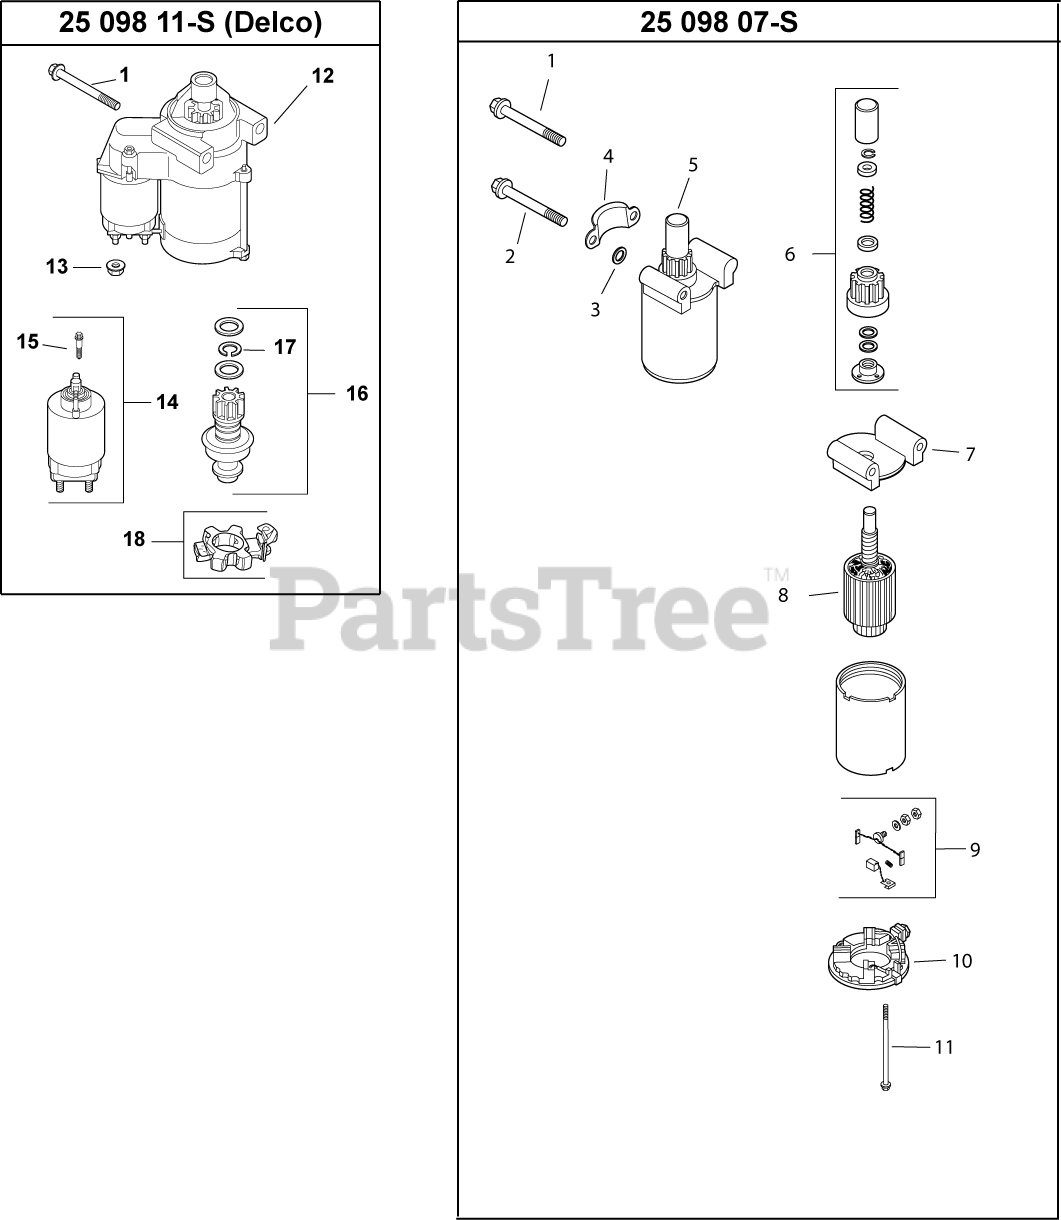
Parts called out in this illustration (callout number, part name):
1	SCREW - USE M-851080-S
2	SCREW, FLG M8X1.25X70
3	WASHER, FLAT 11/32"
4	COVER, PINION
5	ELECTRIC STARTER-BENDIX DRIVE
6	KIT, DRIVE
7	CAP, DRIVE END - (#DSC)
8	ARMATURE - DISCONTINUED
9	BRUSH KIT - (#DSC)
10	CAP - DISCONTINUED
11	BOLT, THRU #10-24X4 13/32" - DISCONTINUED
12	ELECTRIC STARTER - SOLENOID SHIFT USE 25 098 20-s
13	NUT, FLG M8X1.25
14	KIT, SOLENOID
15	SCREW, EXTERNAL TORX HEAD
16	KIT, STARTER PINION
17	RING, RETAINING
18	KIT, BRUSH HOLDER
